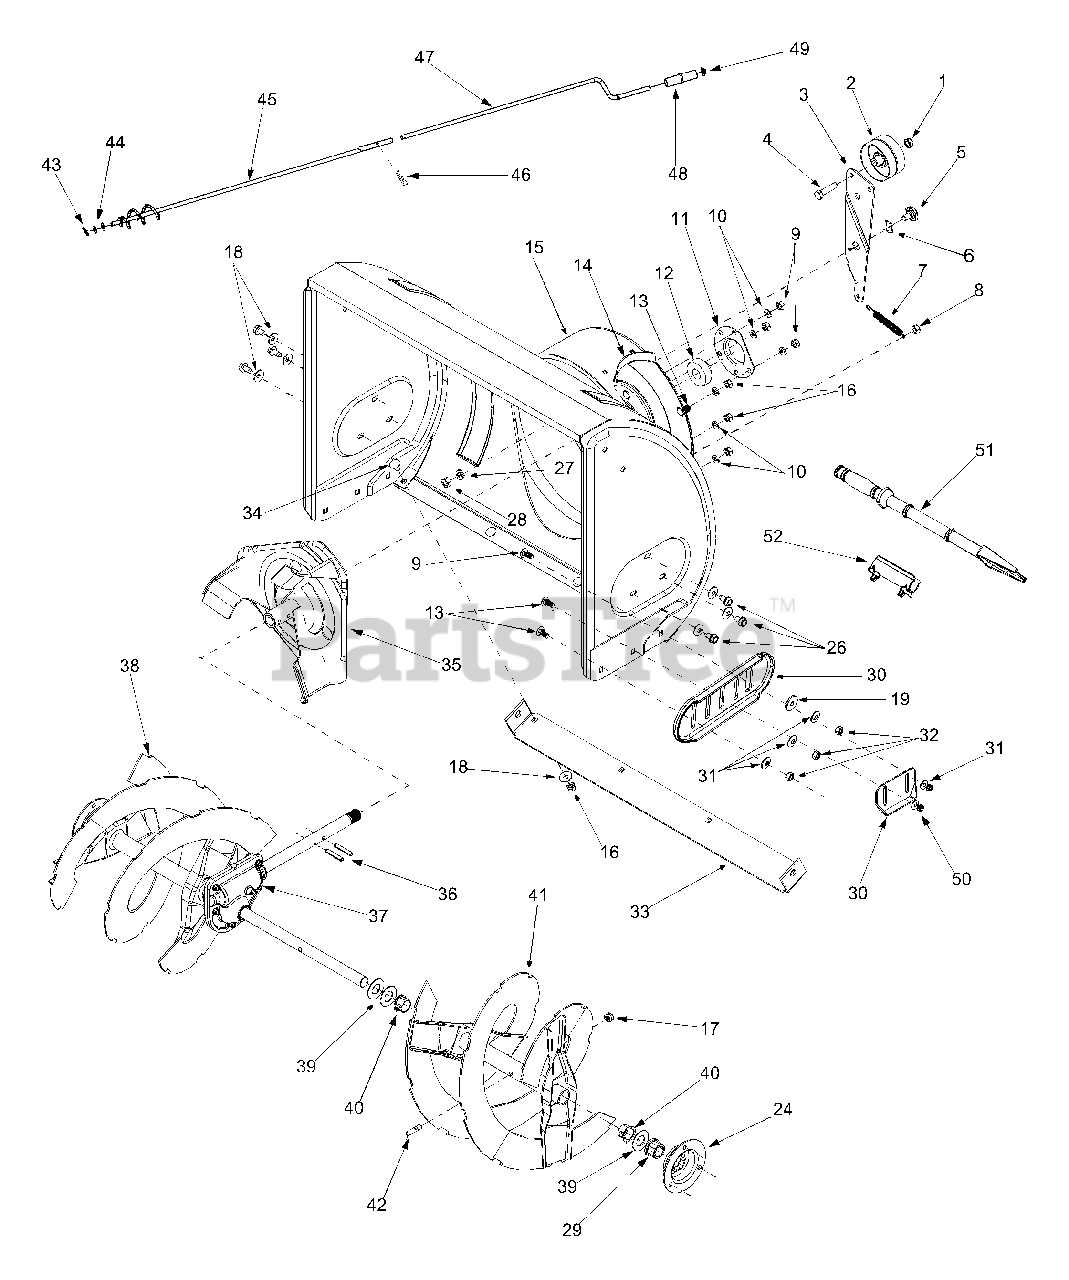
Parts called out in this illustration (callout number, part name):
1	Lock Jam Nut 3/8-24
2	Flat Idler
4	H ex Cap Screw 3/8-24 x 1
5	Shoulder Screw
6	Wave Washer
7	Extension Spring
8	Hex Nut 5/16-18
9	Carriage Bolt, 5/16-18 x 1.00
10	Lock Washer 5/16
11	Bearing Housing
12	Ball Bearing
13	Carriage Bolt, 5/16-18 x .75
17	Lock Nut 5/16-18
18	Belleville Washer
19	Flat Wshr, .344ID x 1.125 OD
26	Hex Screw 5/16-12
27	Lock Washer 3/8
28	Hex Nut 3/8-16
29	Hex Flange Bearing
31	Bell Washer
32	Hex Nut 5/16-18
34	Carriage Bolt 5/16-18 x .62
37	26" Gear Ass'y (H5C3F)
39	Flat Washer
40	Flange Bushing
42	Shear Bolt 5/16-18 x 1.5
43	Hairpin Clip
44	Flat Washer
48	Chute Crank Knob
49	Push Cap
50	Hex Nut 5/16-18
51	Clean-Out Tool
52	Clean-Out Tool Mount
